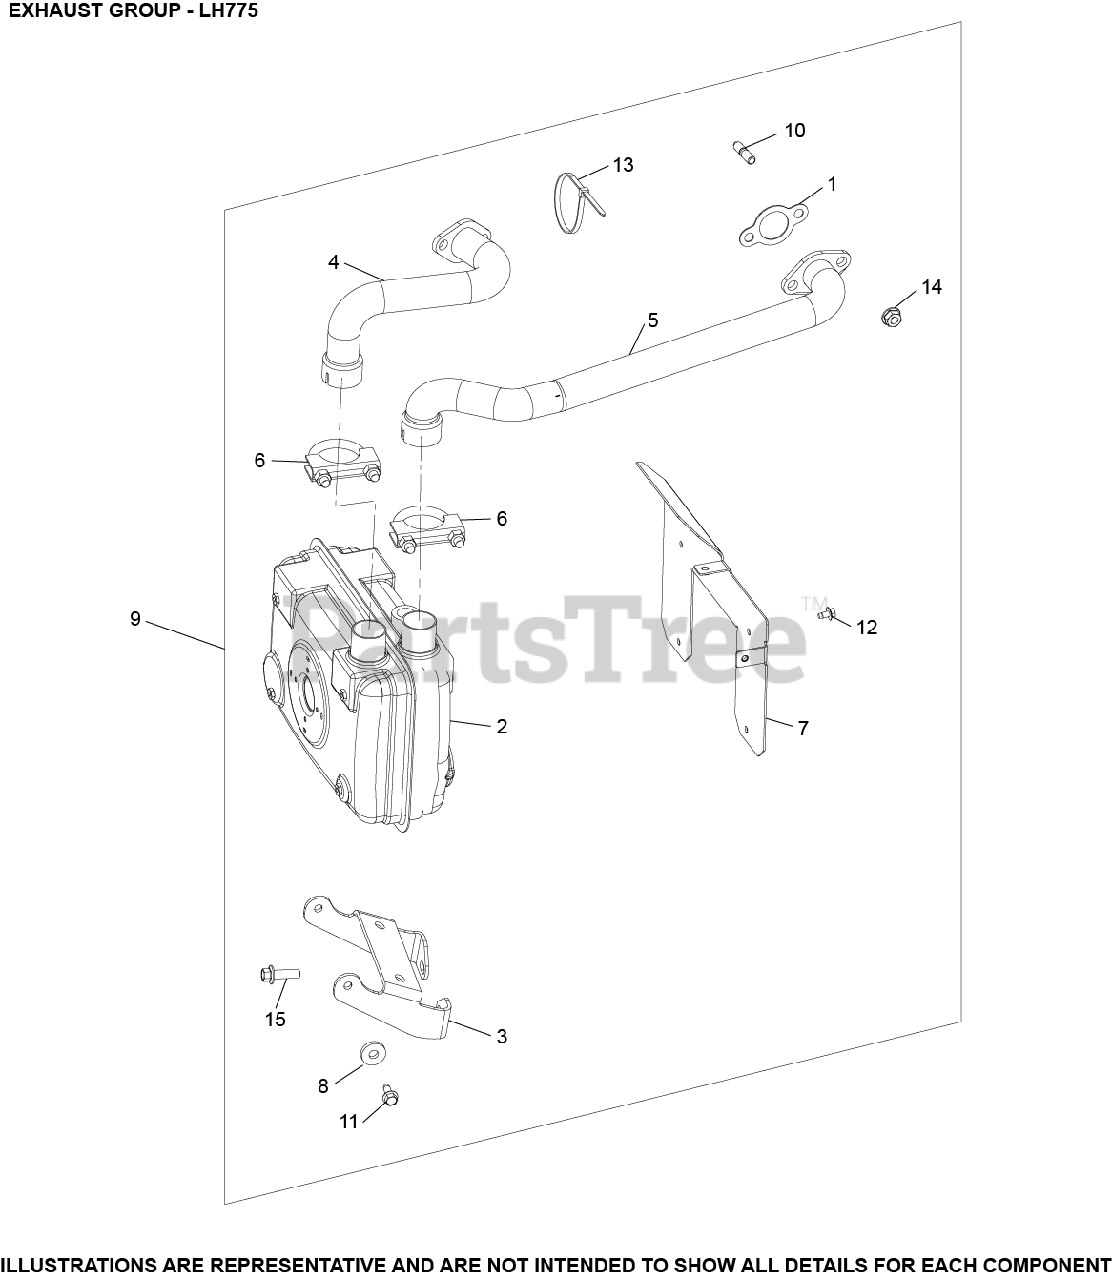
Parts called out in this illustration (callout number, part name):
1	GASKET, EXHAUST
10	STUD, EXHAUST (KM)-USE 25 072 24-S
14	NUT, FLG M8X1.25
